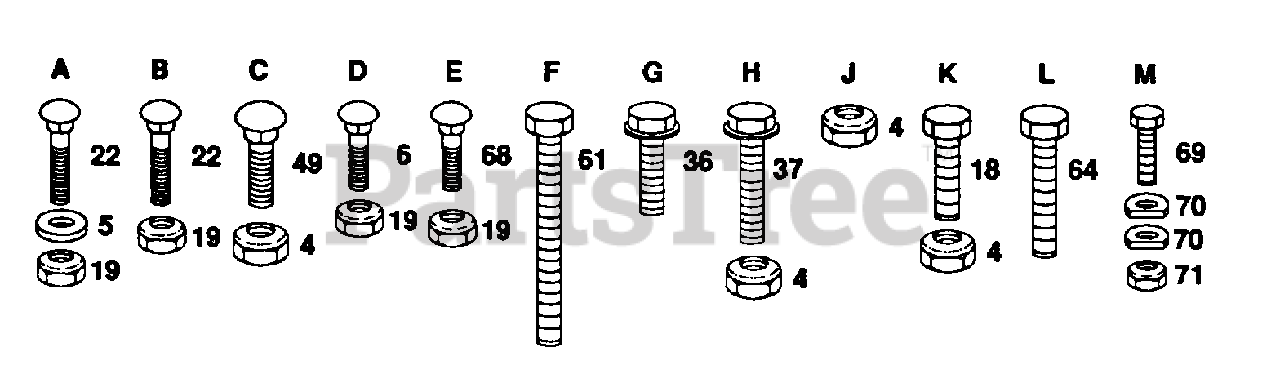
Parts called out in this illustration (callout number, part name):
5	WASHER M
6	BOLT
22	BOLT
36	SCREW
37	SCREW
49	BOLT
61	BOLT
64	BOLT.3/8-14X1.25
69	BOLT LT
70	WASHER T
